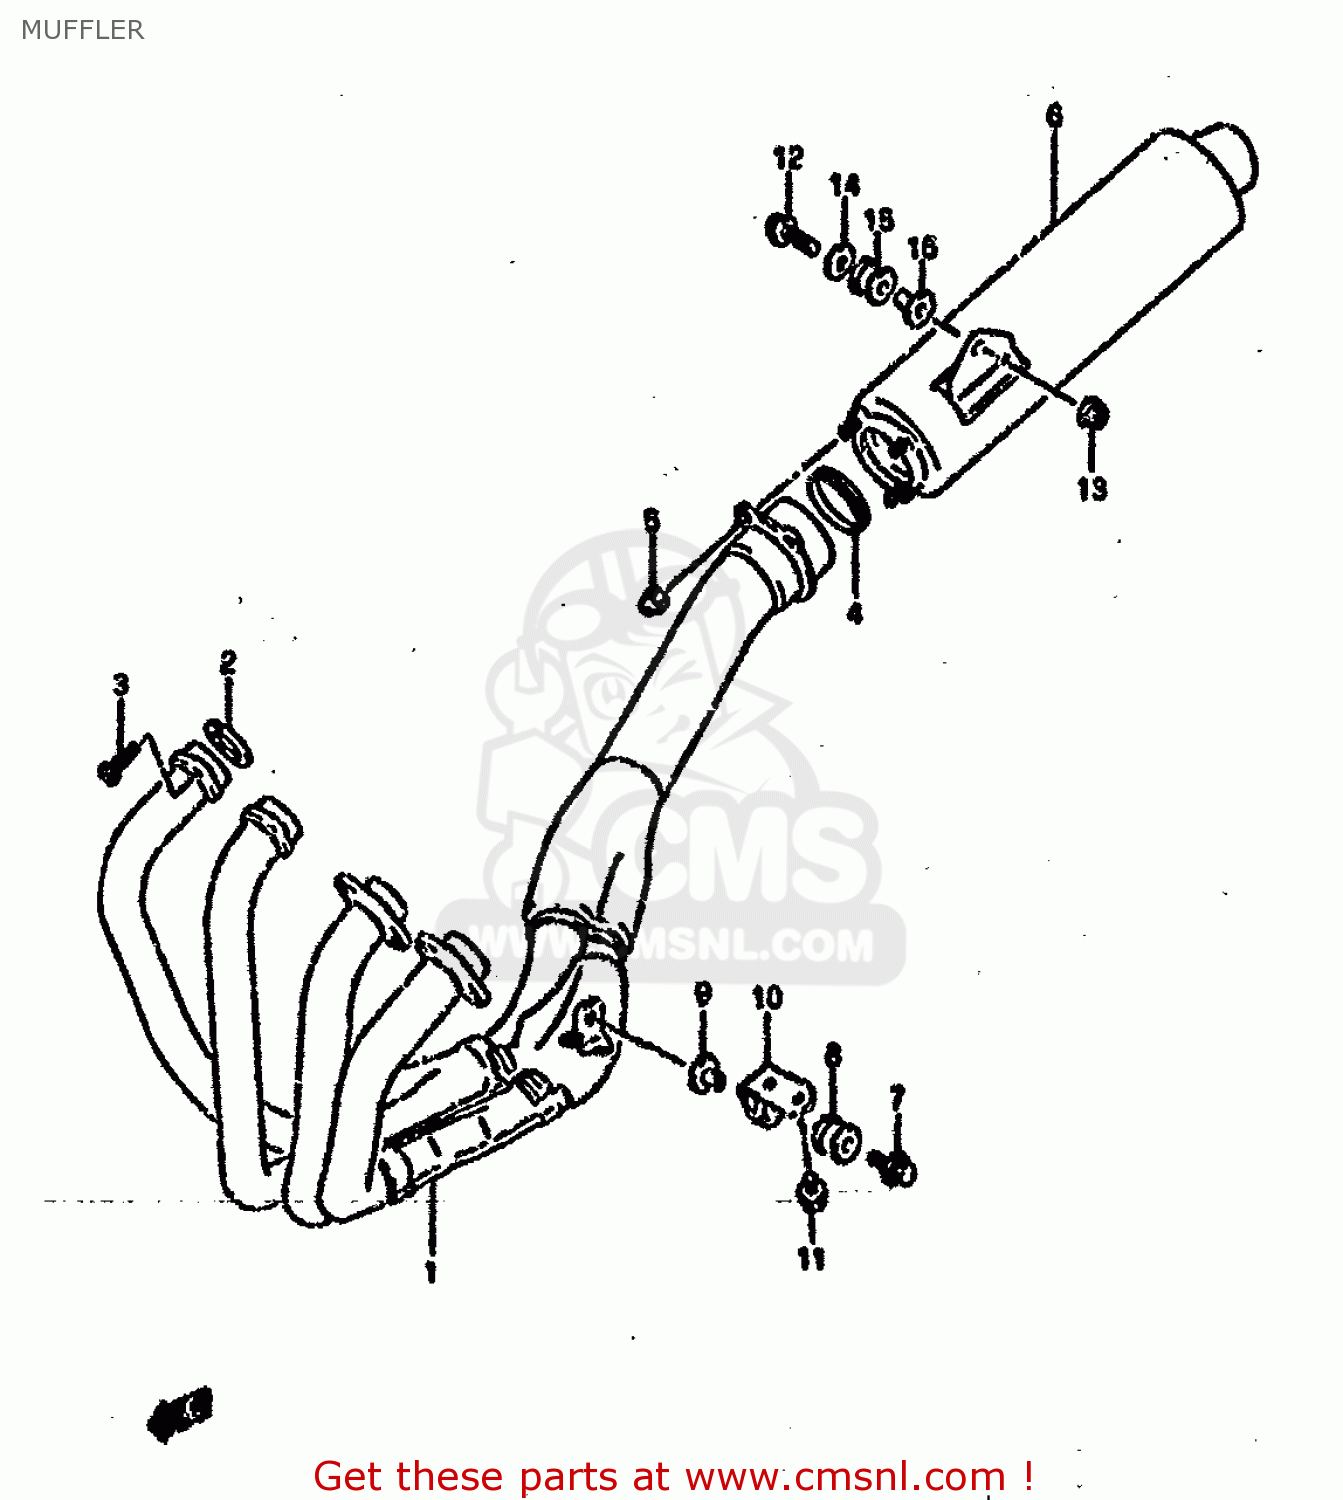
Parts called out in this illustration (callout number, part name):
1	PIPE,EXHAUST
2	GASKET,EXHAUST PIPE
3	BOLT
4	GASKET,MUFFLER JOINT
5	NUT
6	BODY,MUFFLER
7	BOLT 8X45
8	CUSHION
9	SPACER(8.6X12X24.2)
10	DAMPER
11	BOLT(8X20)
12	BOLT
13	NUT
14	WASHER (8.1X33X1.6)
15	CUSHION
16	SPACER(8.6X12X27.1)
